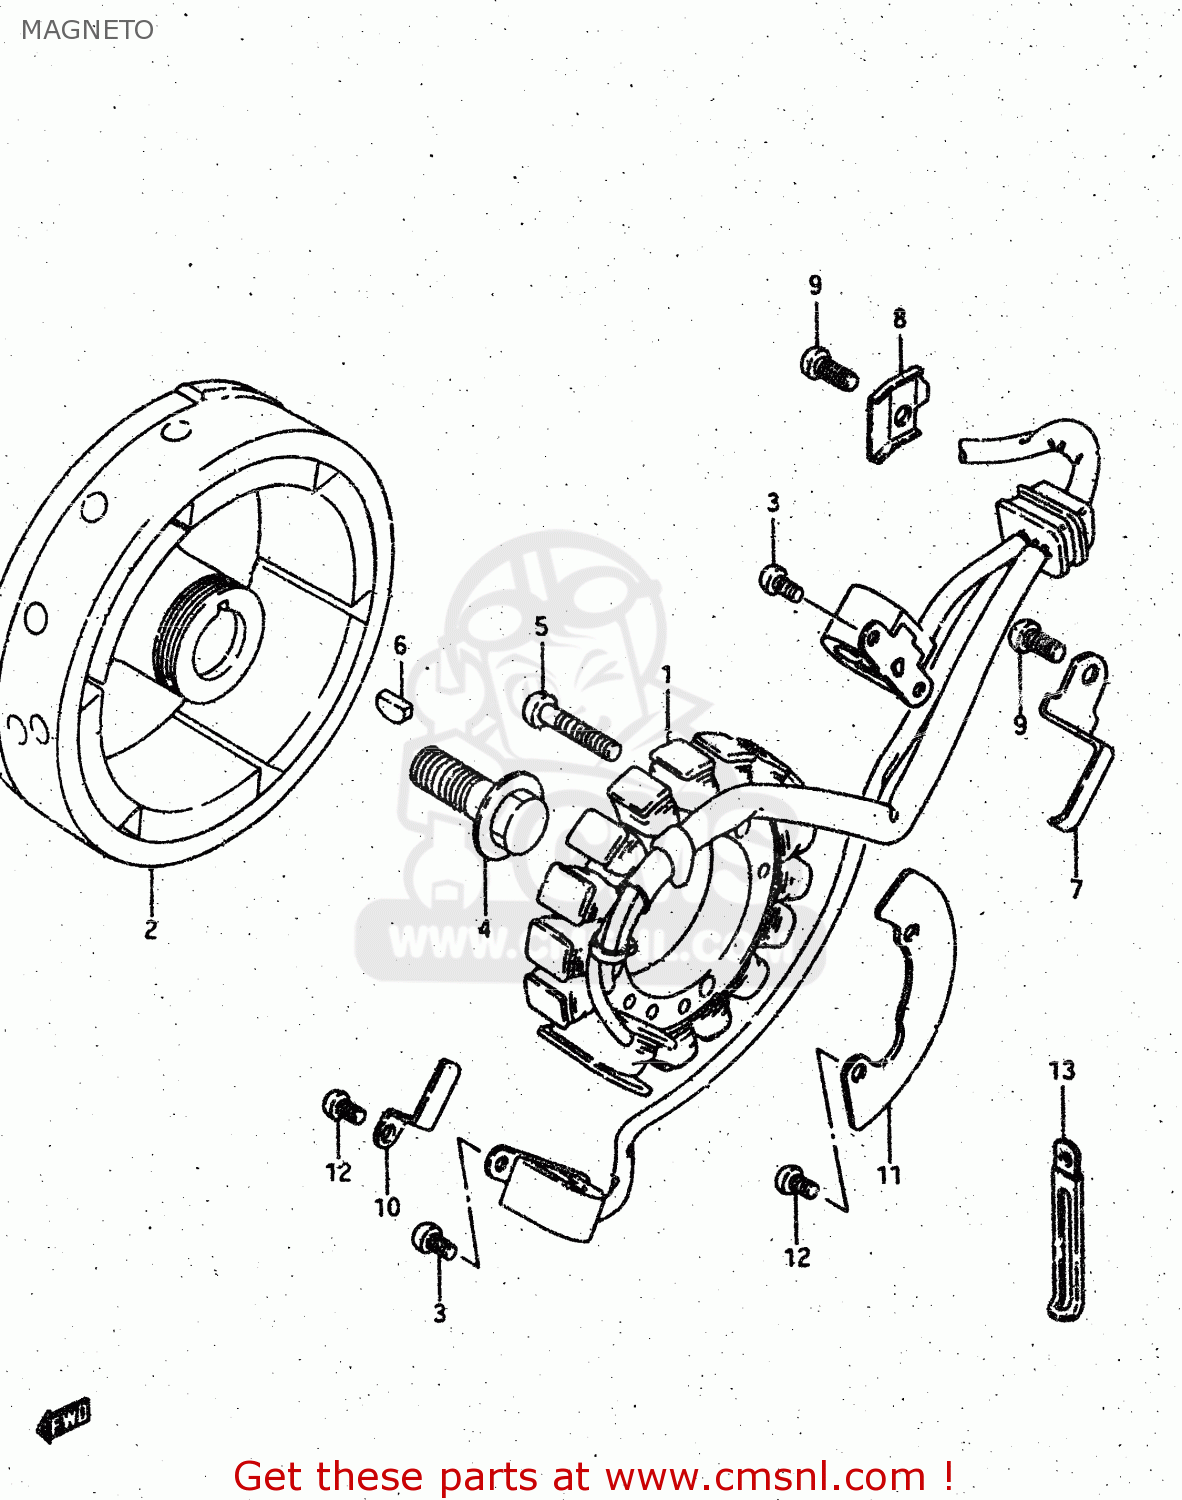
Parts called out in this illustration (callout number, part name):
1	STATOR ASSY
2	ROTOR,FLYWHEEL
3	SCREW
4	BOLT(14X43)
5	SCREW 6X30
6	KEY 4MM
7	CLAMP,MAGNETO LEAD WIRE
8	CLAMP,MAGNETO LEAD WIRE
9	SCREW
10	CLAMP
11	CLAMP
12	SCREW
13	CLAMP
